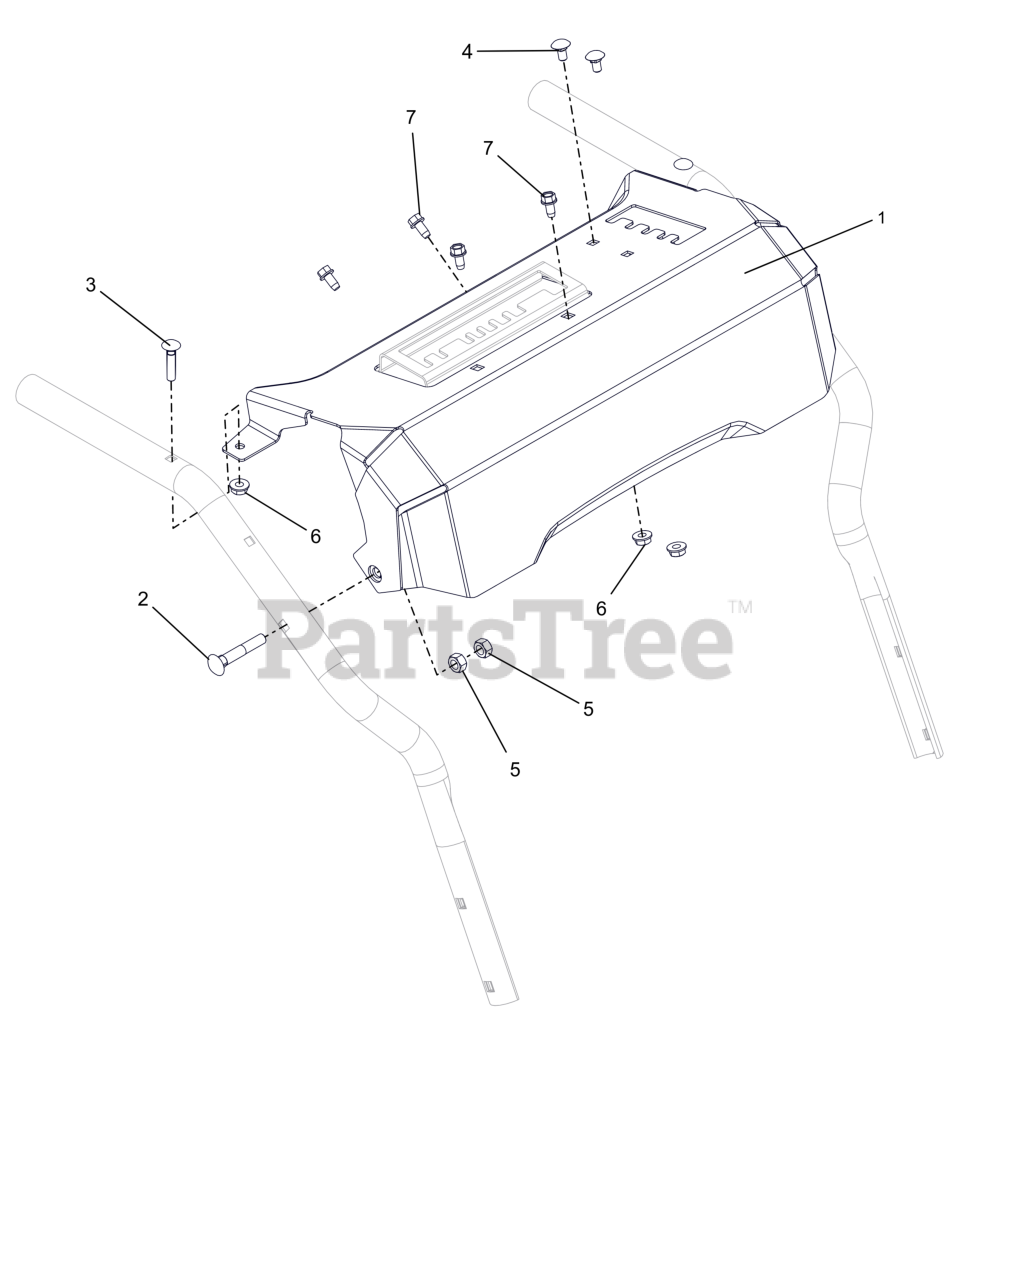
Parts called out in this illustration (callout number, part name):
1	CTRL PANEL W/DECAL-SNOTEK REMO
2	BLT-RDHDXLSQNK .31-18X2.0 G5YZ
3	BLT-RDHDXLSQNK.25-20X1.25 G5ZC
4	BLT, RHSN .25-20X.500 G5 ZCC
5	NUT,LK-CTR .31-18 GA ZCC
6	NUT-LK-TOP-FLG .250-20 GF ZCC
7	SCR-TAP .25-20X.50 HWH ZCC
